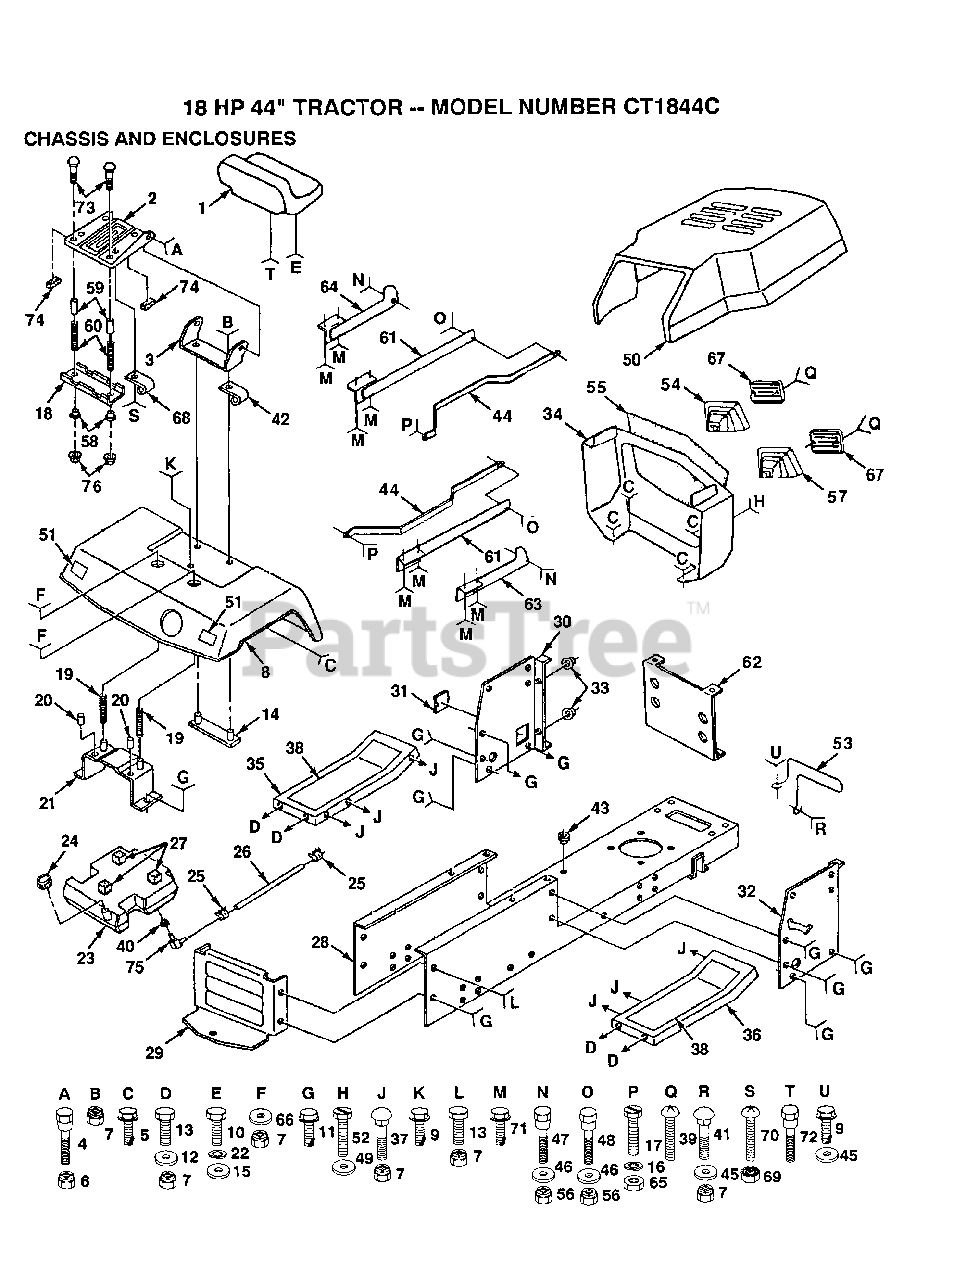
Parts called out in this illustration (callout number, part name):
3	BRKT PIVOT SEAT
5	SCREW LT
9	SCREW GTV
10	BOLT
11	SCREW
12	WASHER
15	WASHER
16	LOCKWASHER
17	BOLT LT
18	BRKT SWITCH
19	SPRING COMPRESSIO
20	NUT-PUSH YT
22	LOCKWASHER
25	HOSE CLAMP
27	PAD-SPACER LT
28	CHASSIS
31	COVER ACCESS
33	SNAP BUSHING T
37	BOLT
38	FOOTREST PAD
40	BUSHING OUTLET T
41	BOLT D
42	CLIP T
45	WASHER HYT
47	BOLT T
48	"BOLT,SHOULDER"
51	REFLECTOR-TAIL YT
52	SCREW
53	GUARD MUFFLER HYT
55	SCREEN GRILL GTV
58	BUSHING
59	SPACER SPLIT
60	SPRING COMPRESSED
61	STRAP ASSY-REAR T
63	STRAP ASSY T
64	STRAP ASSY T
66	WASHER
69	"NUT,KEPS"
72	"BOLT,SHOULDER"
74	STRIP FORM
75	FUEL TANK STEM GT
